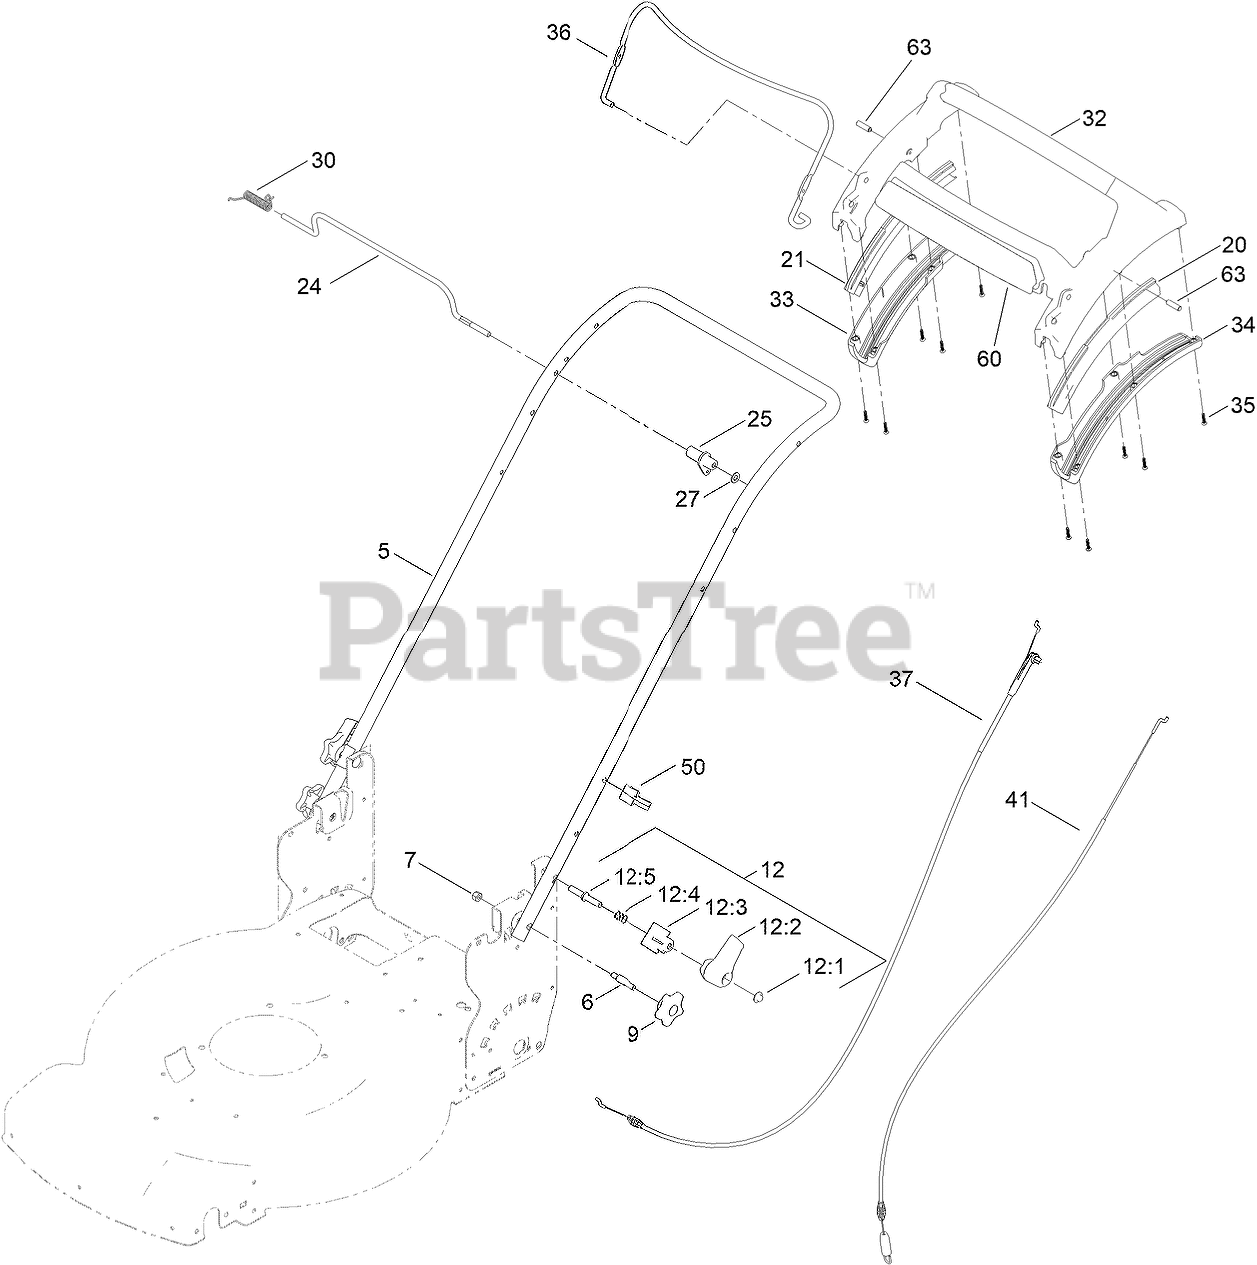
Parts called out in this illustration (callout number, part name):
5	HANDLE-CURVED
6	BOLT-SHOULDER, HANDLE
7	NUT-HEX
9	KNOB-HANDLE
12	QUICK RELEASE ASM
12:1	NUT-PUSH
12:2	LEVER-RELEASE
12:3	ANCHOR-SPRING
12:4	SPRING-COMPRESSION
12:5	ROD-RELEASE
20	GUIDE-CURVED, LH (RWD)
21	GUIDE-CURVED, RH (RWD)
24	ROD-CONTROL, TRACTION
25	LEVER-TRACTION, RWD
27	WASHER-PLAIN
30	SPRING-TORSION
32	HANDLE-PERSONAL PACE, CURVED
33	BOTTOM-HANDLE, RH
34	BOTTOM-HANDLE, LH
35	SCREW-PPH
36	BAIL-BRAKE
37	CABLE-BRAKE, PP BS
41	CABLE-TRACTION, RWD (PP)
50	GUIDE-CABLE
60	DECAL - ADS, HANDLE
63	PIN-HANDLE, PP
